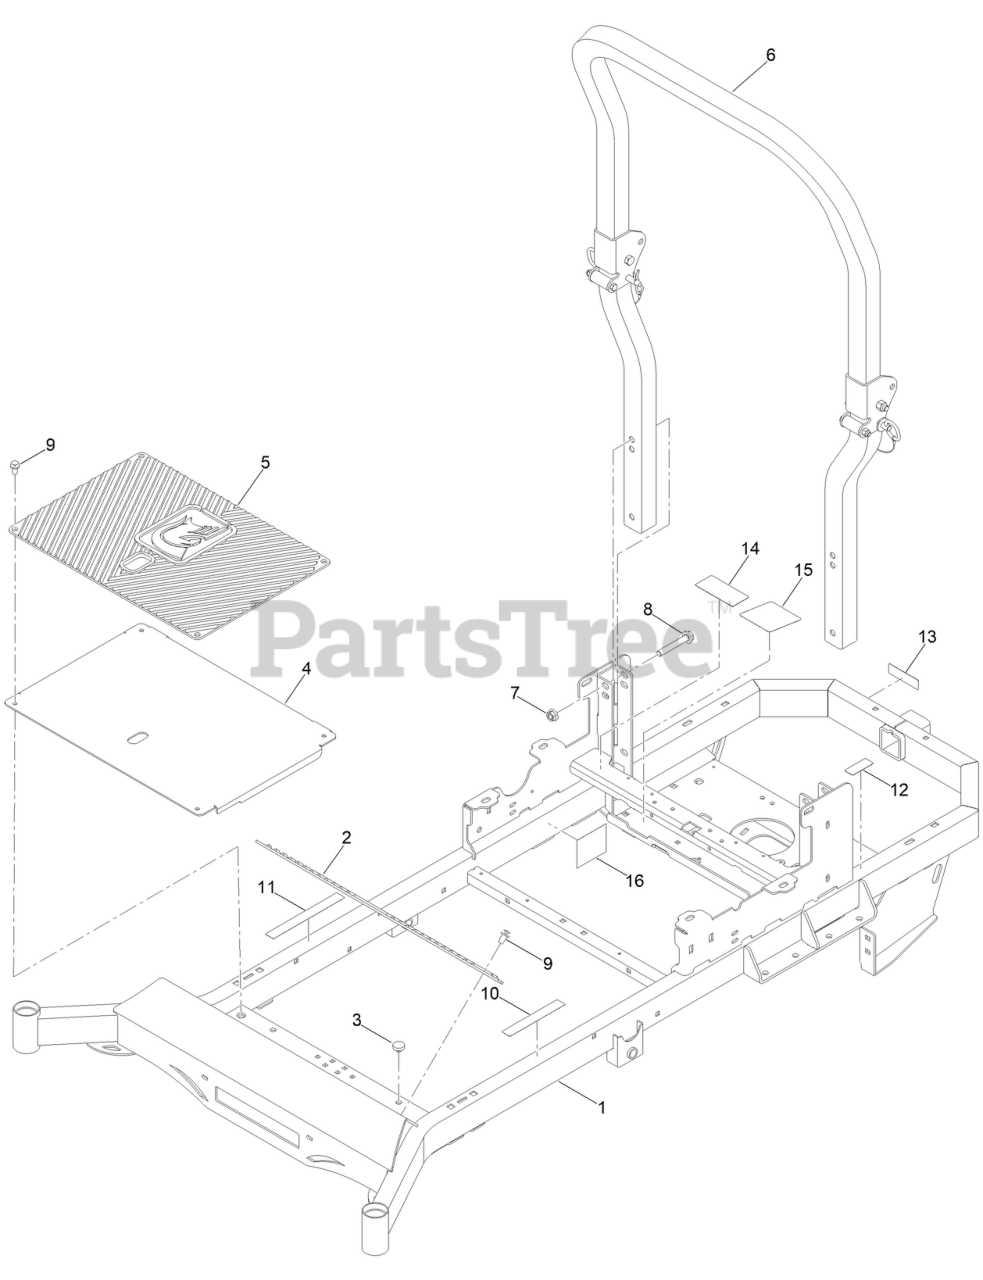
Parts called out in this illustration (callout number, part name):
1	FRAME-ZTR
1	FRAME ASM-DECALS
2	MWR RUBBER FOOT REST MAT
3	PUSH-IN RUBBER BUMPER MWR FLOOR
4	MWR FLOORBOARD BLACK
5	MWR LOGO FLOOR MAT
7	1/2-13 HEX STOVER LOCKNUT GR C ZINC
9	8MM PUSH TYPE RETAINER NYLON BLACK
10	DECAL-WARNING
11	DECAL-WARNING
12	DECAL-HOT SURFACE
13	DECAL-HITCH
14	DECAL-WARNING
15	DECAL-PUMP BELT ROUTING-PARKER
16	DECAL-EPA
